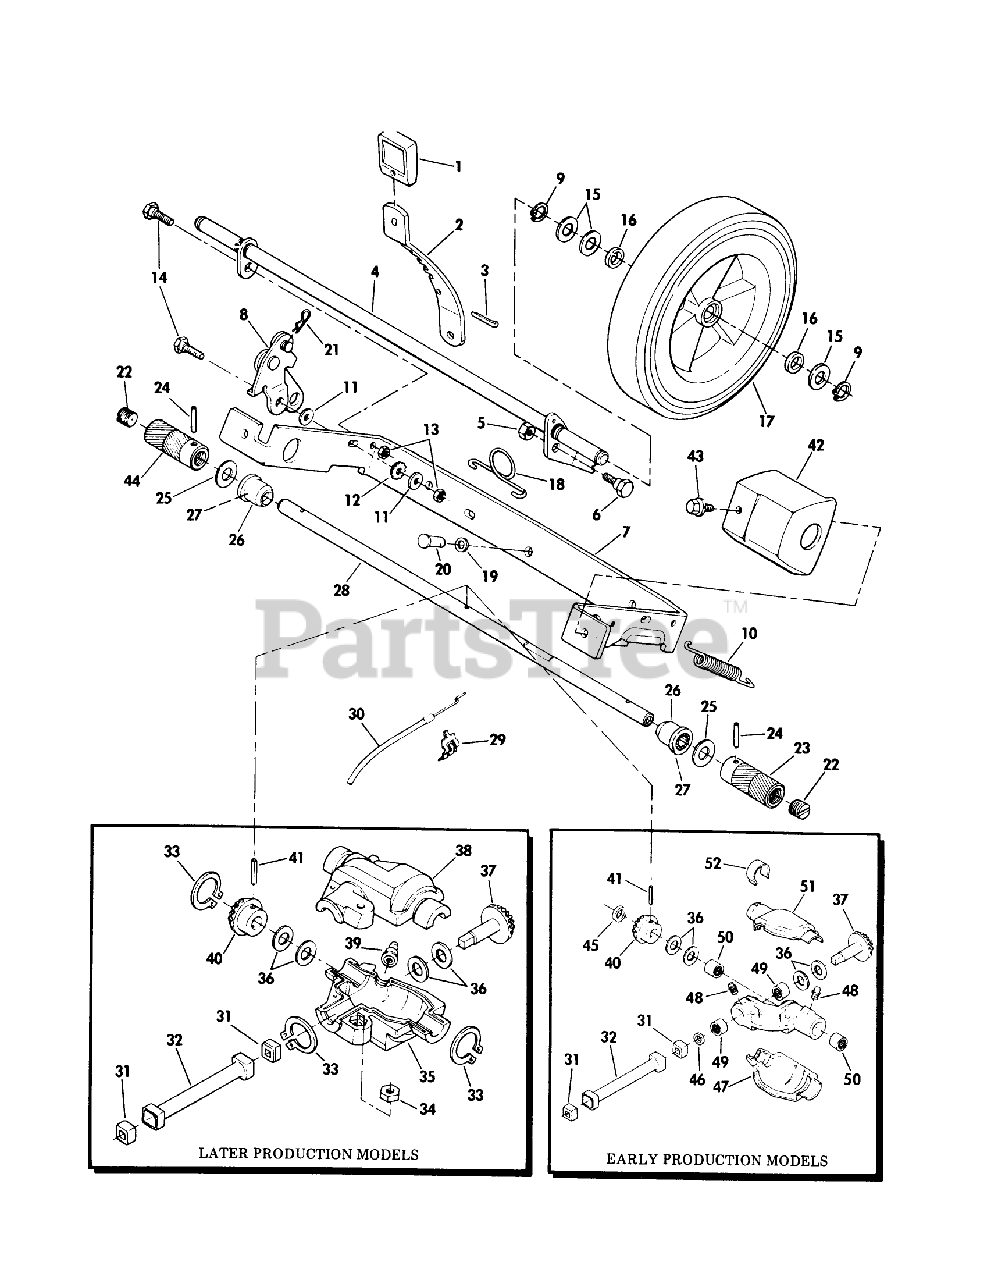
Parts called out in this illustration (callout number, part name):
1	KNOB
2	LEVER
5	LOCKNUT E
6	BOLT RB&W
9	RET RING
10	SPRING
11	WASHER S
13	STOP NUT
14	BOLT RB&W
15	SPACER
16	WASHER
18	SPRING N.A.S
19	WASHER SPRING LAR
20	PIN
22	GREASE PLUG
24	PIN
27	BEARING AY F
28	DRIVE SHFT TAG AY
31	BUSHING
34	LOCKNUT E
36	THRUST WASHER
39	ZERK FITTING
41	ROLL PIN
42	GUARD
45	WASHER
46	O Ring
48	**FITTING LINCOLN
49	NEEDLE BEARING
51	GEAR COVER UPPER
